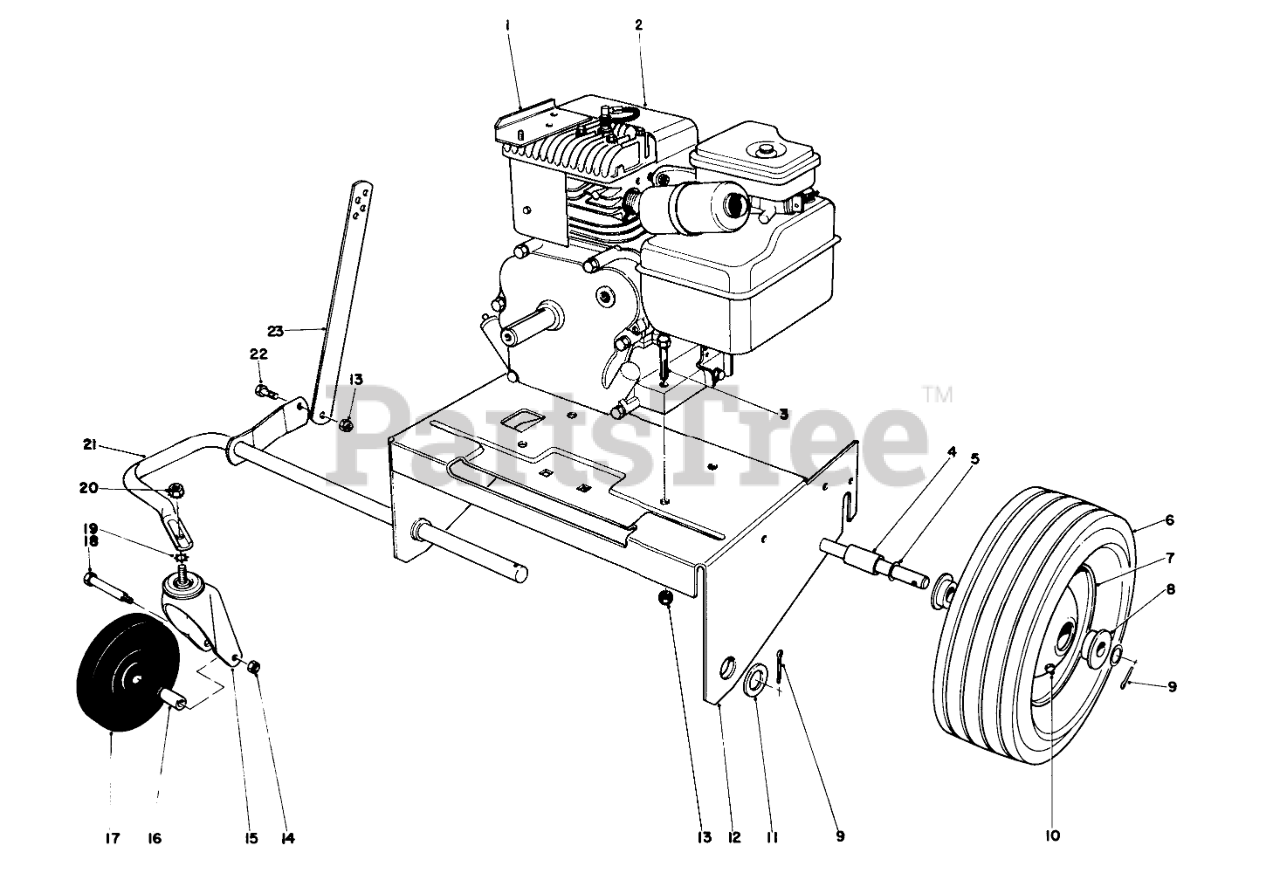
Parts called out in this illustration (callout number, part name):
1	MOUNTING BRKT WA
2	Engine
3	SCREW-HH
4	SPACER-AXLE
5	WASHER
6	3.50X10 SEMIPNEU TIRE
7	Rim
8	BUSHING
9	PIN-COTTER
10	FITTING-GREASE
11	WASHER-FLAT
12	BLWR ENG MTG PLT WA
13	NUT-LOCK, NI
16	Wheel Bushing
17	Wheel
19	WASHER-LOCK
21	Front Wheel Support
22	SCREW-HH
23	Bar Height Adjustment
